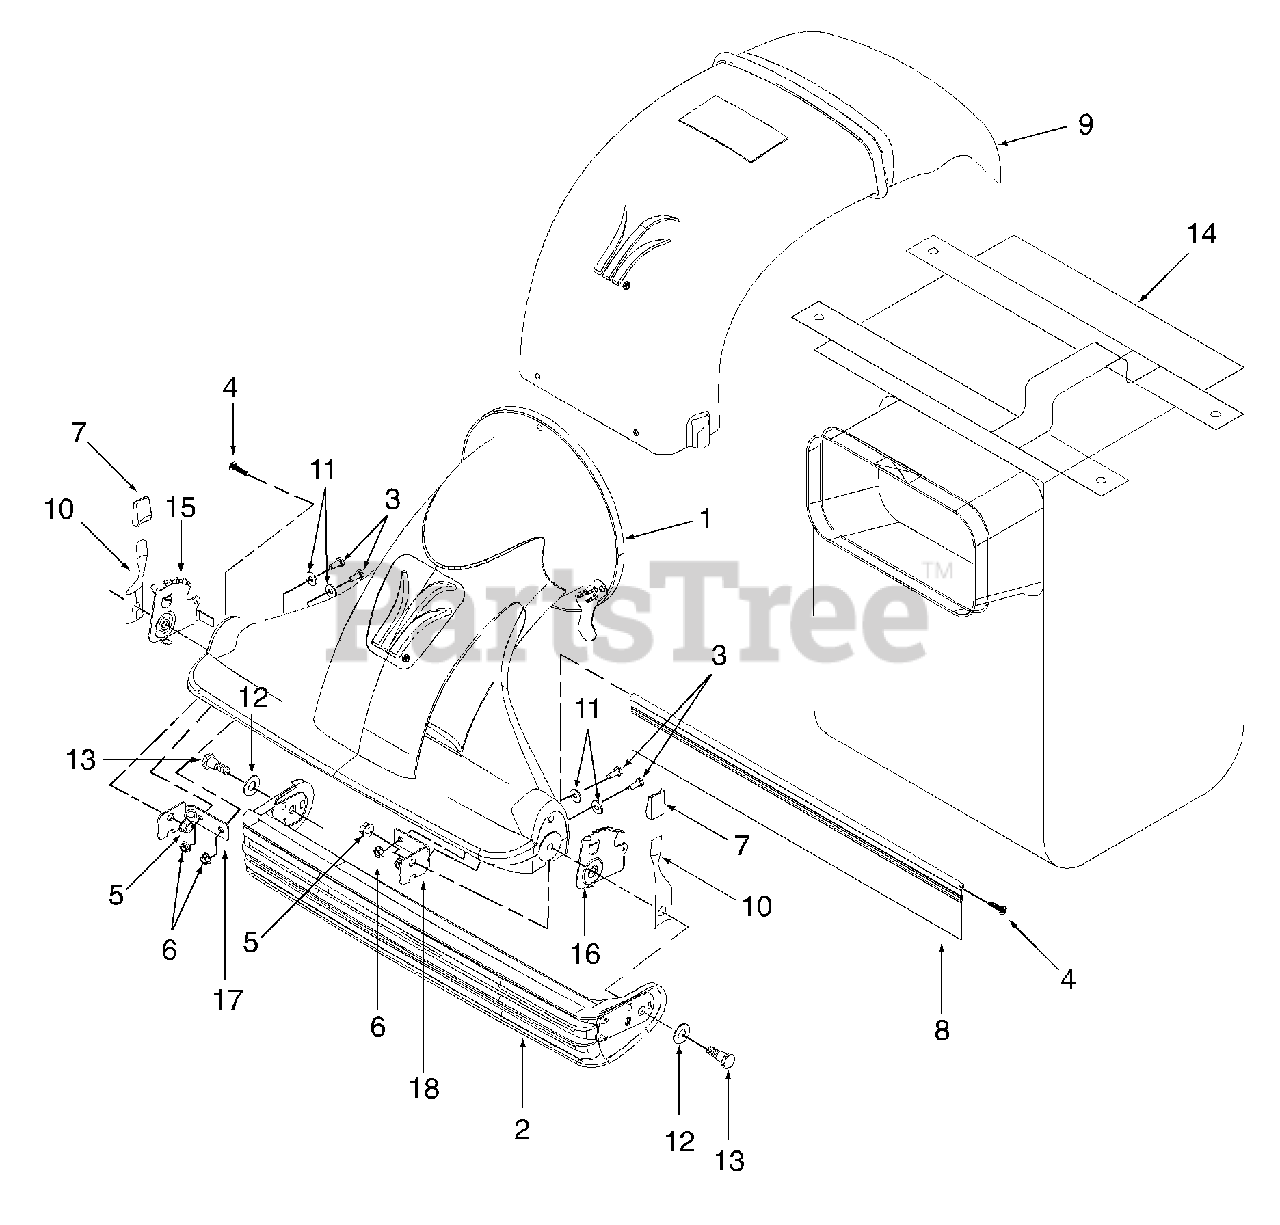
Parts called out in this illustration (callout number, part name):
1	Nozzle Assembly, Yellow
2	Door Assembly, Yellow
3	Screw, Hex Cap, 1/4-20 x .625
4	Screw, Truss Hd Tapp
5	Nut, Hex Flange Lock, 3/8-16
6	Nut, Hex Flange Lock, 1/4-20
7	Knob, Height Adj.
8	Flap, Nozzle Rear
9	Discharge Chute
10	Spring Lever
11	Washer, Flat, .28 x .74 x .06
12	Washer, Flat, .510 x 1.20 x .060
13	Screw, Shoulder, .50 x .545 x 3/8-16
14	Bag, 3 Bushel
